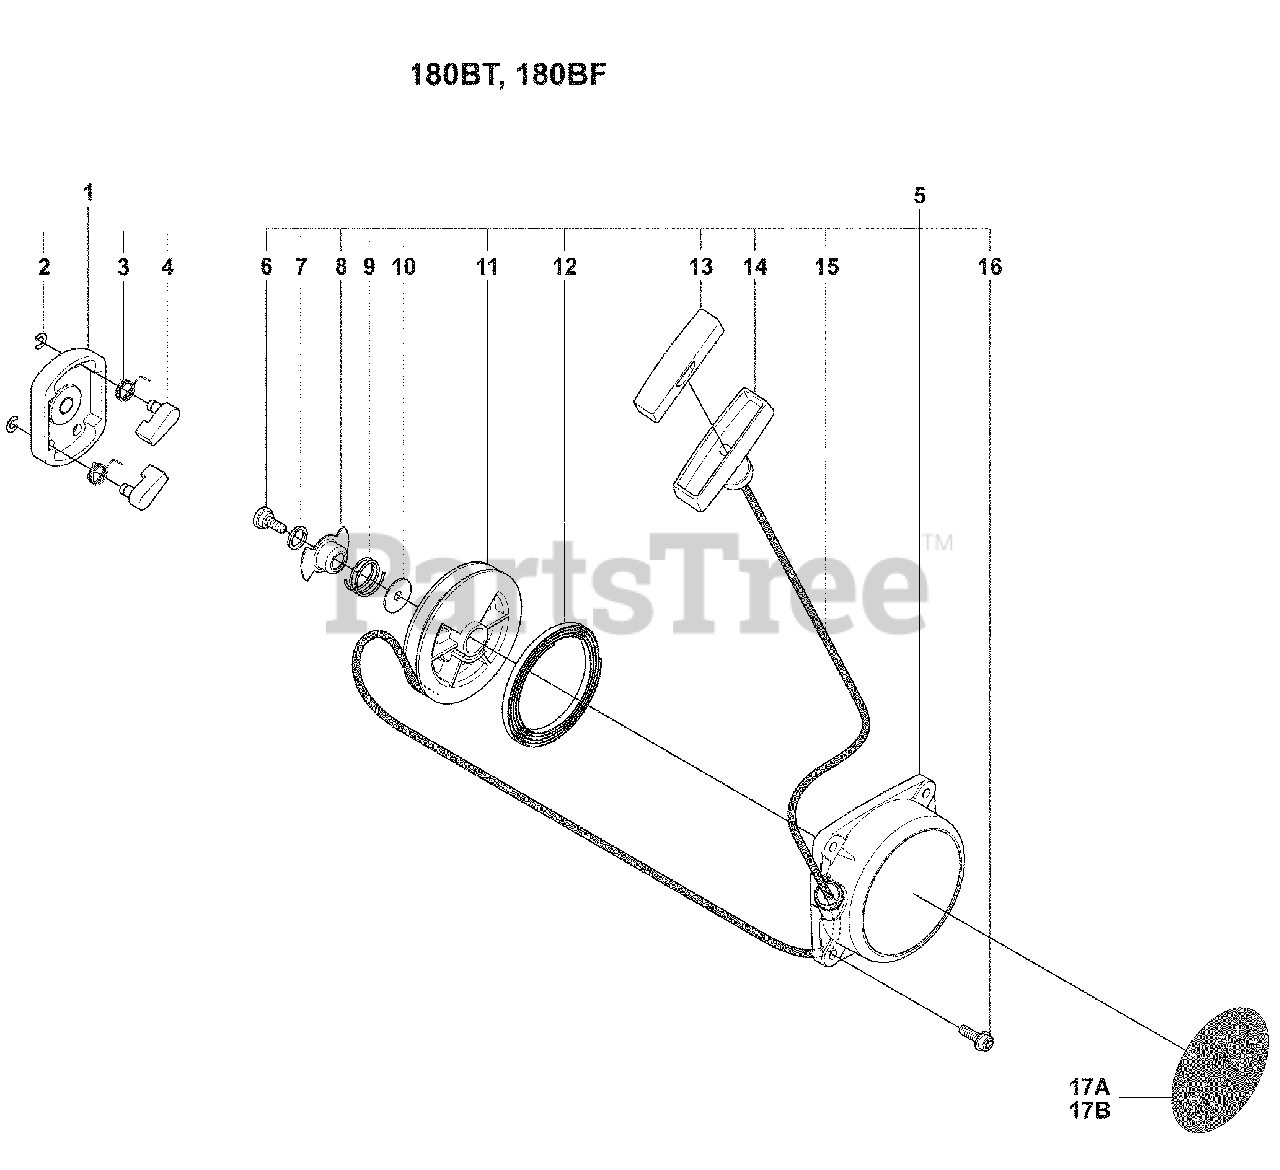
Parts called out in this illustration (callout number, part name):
1	Pulley Assembly
2	E-Ring
5	Recoil Assembly
6	Screw
7	Washer
8	Friction Plate
9	Friction Spring
10	Washer
11	Reel
12	Spring
13	Cover
14	Knob
16	Bolt
17A	LABEL RECOIL
17B	LABEL RECOIL
